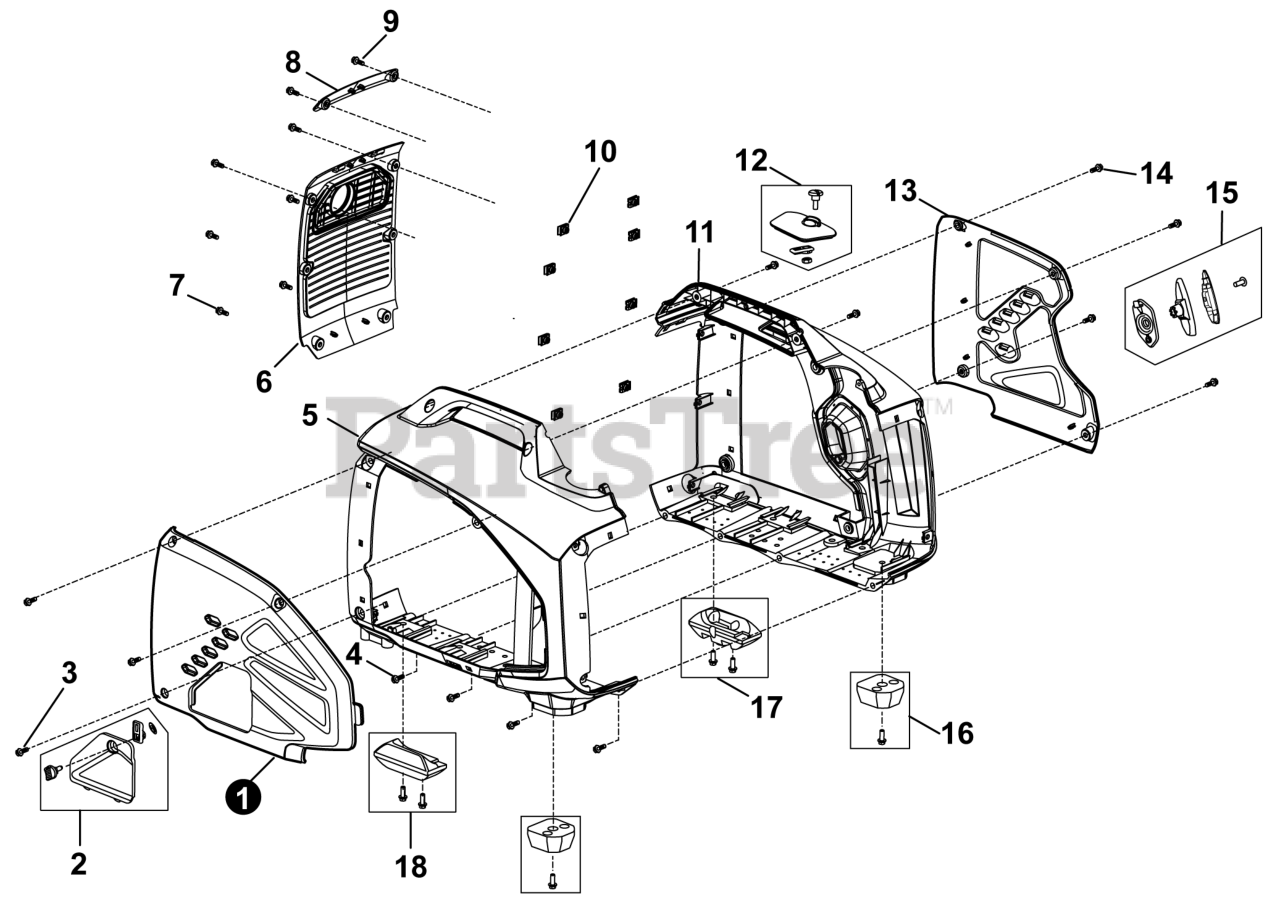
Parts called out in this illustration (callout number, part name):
1	PANEL, LEFT SIDE
2	DOOR, LEFT MAINTENANCE
5	HOUSING, LEFT SIDE
6	COVER, MUFFLER SIDE
8	PLATE, BRANDING
11	HOUSING, RIGHT SIDE
12	DOOR, SPARK PLUG MAINTENANCE
13	PANEL, RIGHT SIDE
15	ROPE GUIDE ASSY., STARTING
16	FOOT, FRAME SUPPORT
17	FOOT, FRAME SUPPORT (RIGHT)
18	FOOT, FRAME SUPPORT (LEFT)
